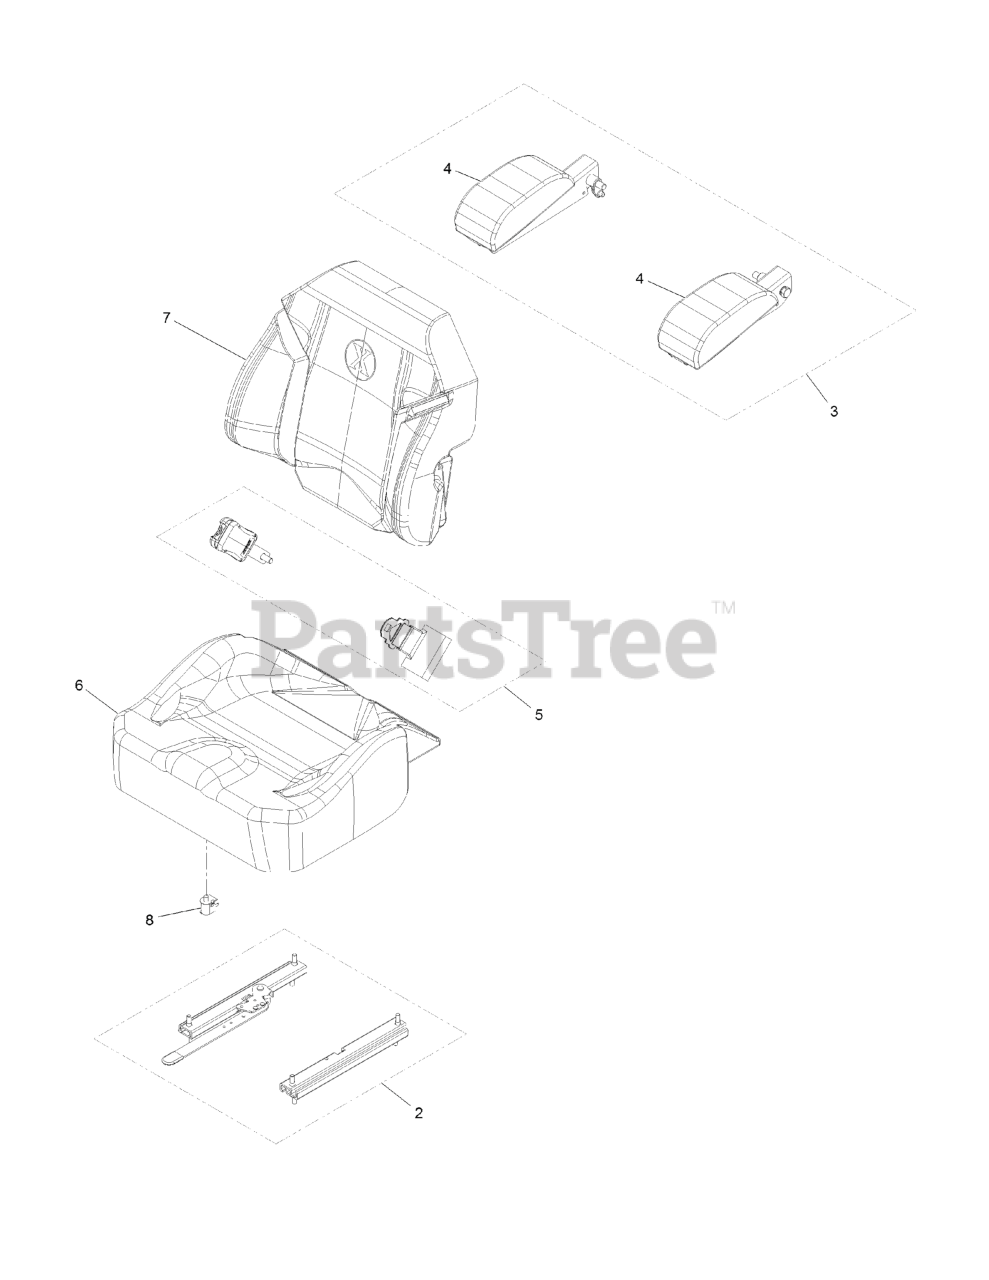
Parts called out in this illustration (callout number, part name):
2	SEAT TRACK SET
3	KIT-ARM REST SET
4	KIT-ARM REST PADS
5	SEAT BELT KIT
6	SEAT CUSHION COVER
7	SEAT BACK COVER
8	SWITCH-BAIL
